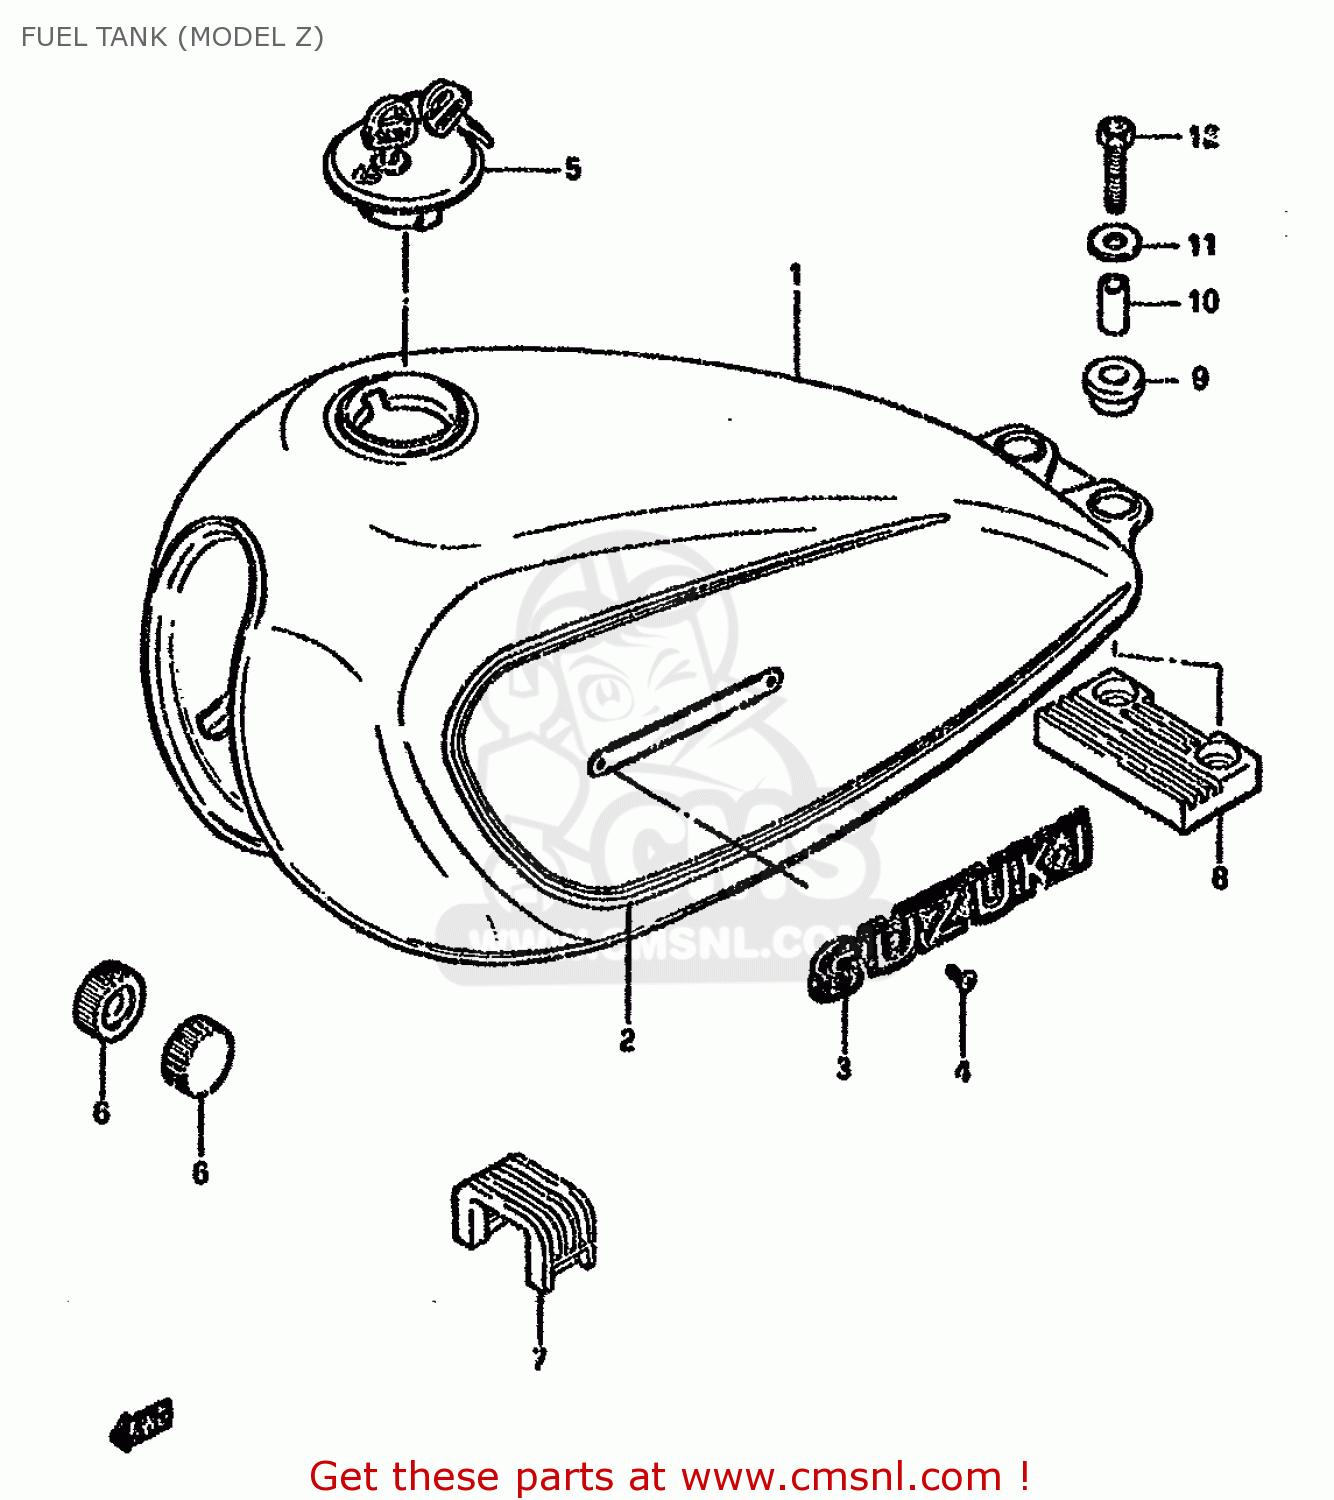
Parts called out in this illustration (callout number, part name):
1	TANK,FUEL (RED)
2	TAPE SET,FUEL TANK
3	EMBLEM,FUEL TANK
4	SCREW 3X6
5	CAP SET,FUEL TANK
6	CUSHION
7	CUSHION,FUEL TANK UPR FR
8	CUSHION,TANK RR NO.1
9	CUSHION
10	SPACER(6.5X10.5X22.5)
11	WASHER(6,5X22X1.6)
12	BOLT(6X35)
